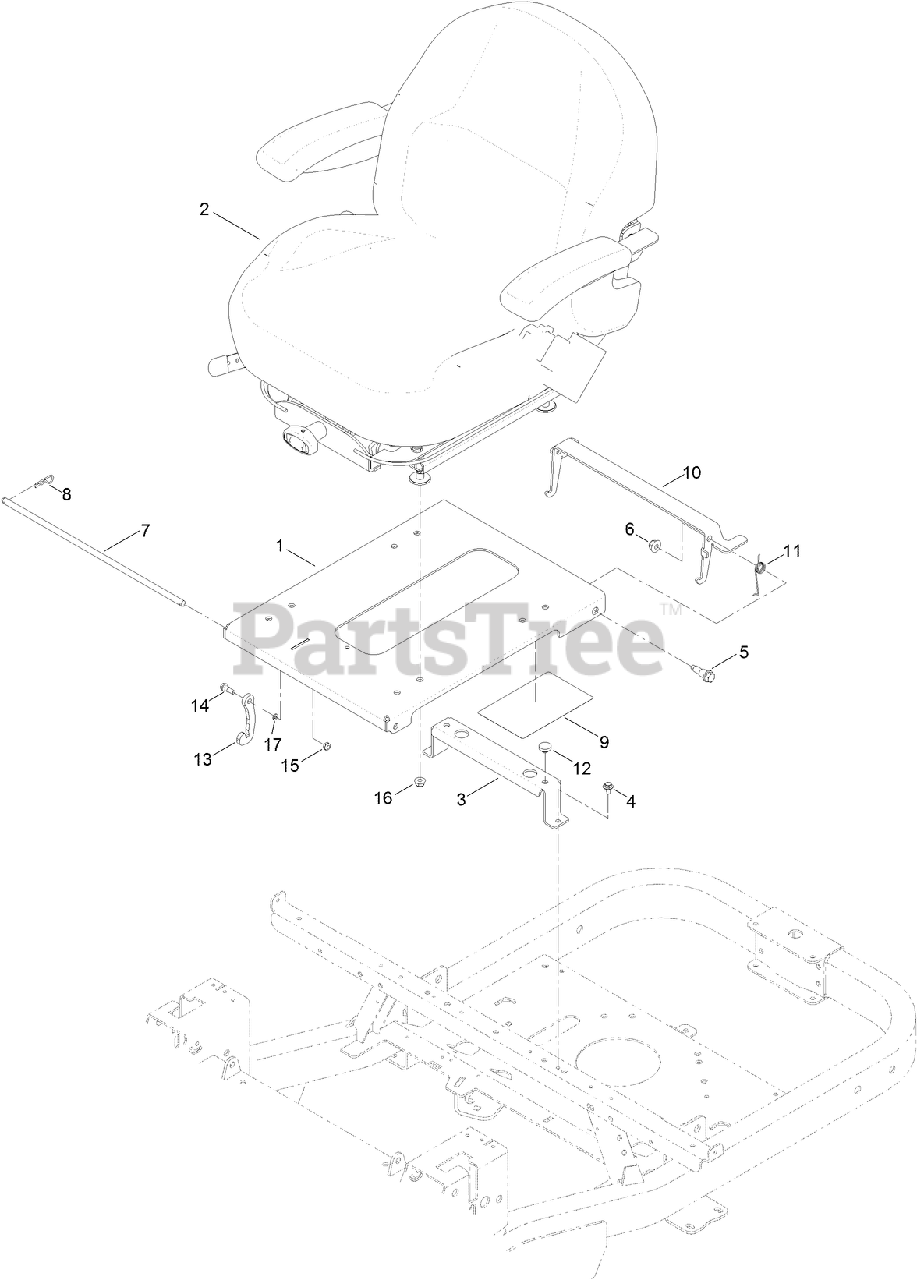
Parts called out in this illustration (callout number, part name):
1	SEAT PAN ASM
3	SEAT-SUPPORT, REAR
4	SCREW-HHFTF
5	BOLT-SHOULDER
6	NUT-HF, NI
7	ROD-STOP
8	PIN-COTTER
9	DECAL-MAINTENANCE
10	LATCH-SEAT
11	TORSION-SPRING
12	BUMPER
13	STOP-SEAT
14	BOLT-SHOULDER
15	NUT-LOCK, NI
16	NUT-HF, NI
17	WASHER
